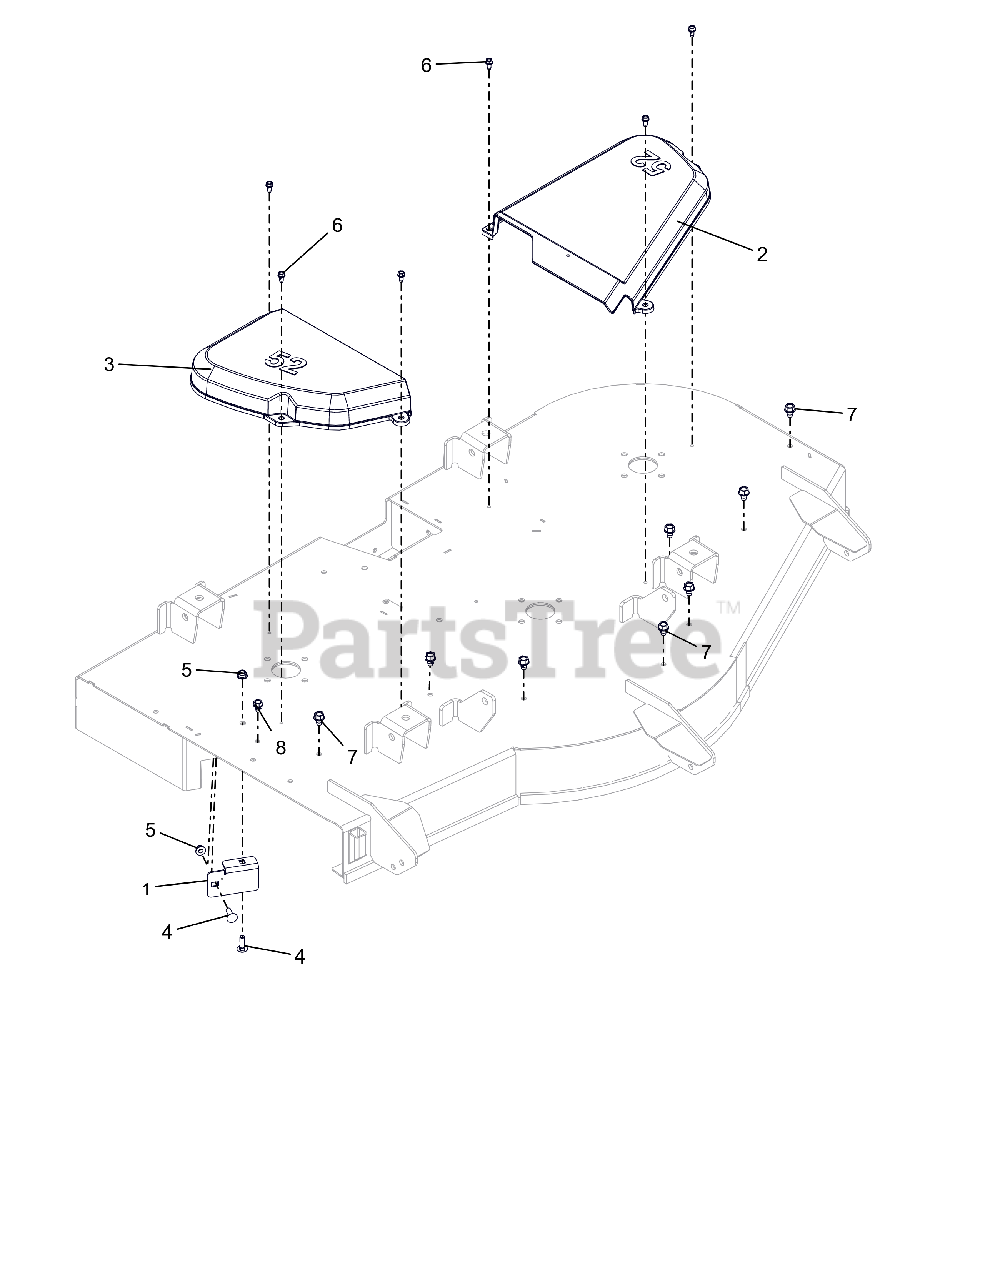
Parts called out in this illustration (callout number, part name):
1	STRIP, DEFLECTOR - 52"
2	COVER, BELT 52" LH
3	COVER, BELT 52" RIGHT
4	BLT,RHSN .31-18X1.00 G5 ZCC
5	NUT,LK-NYL-FLG .31-18 G5ZC120
6	SCR-TAP .25-20X.50 HWH ZCC
7	SCR,TAP .375-16X.50 HWH TR ZCC
8	SCR,TAP .312-18X.50 HWH TR ZCC
